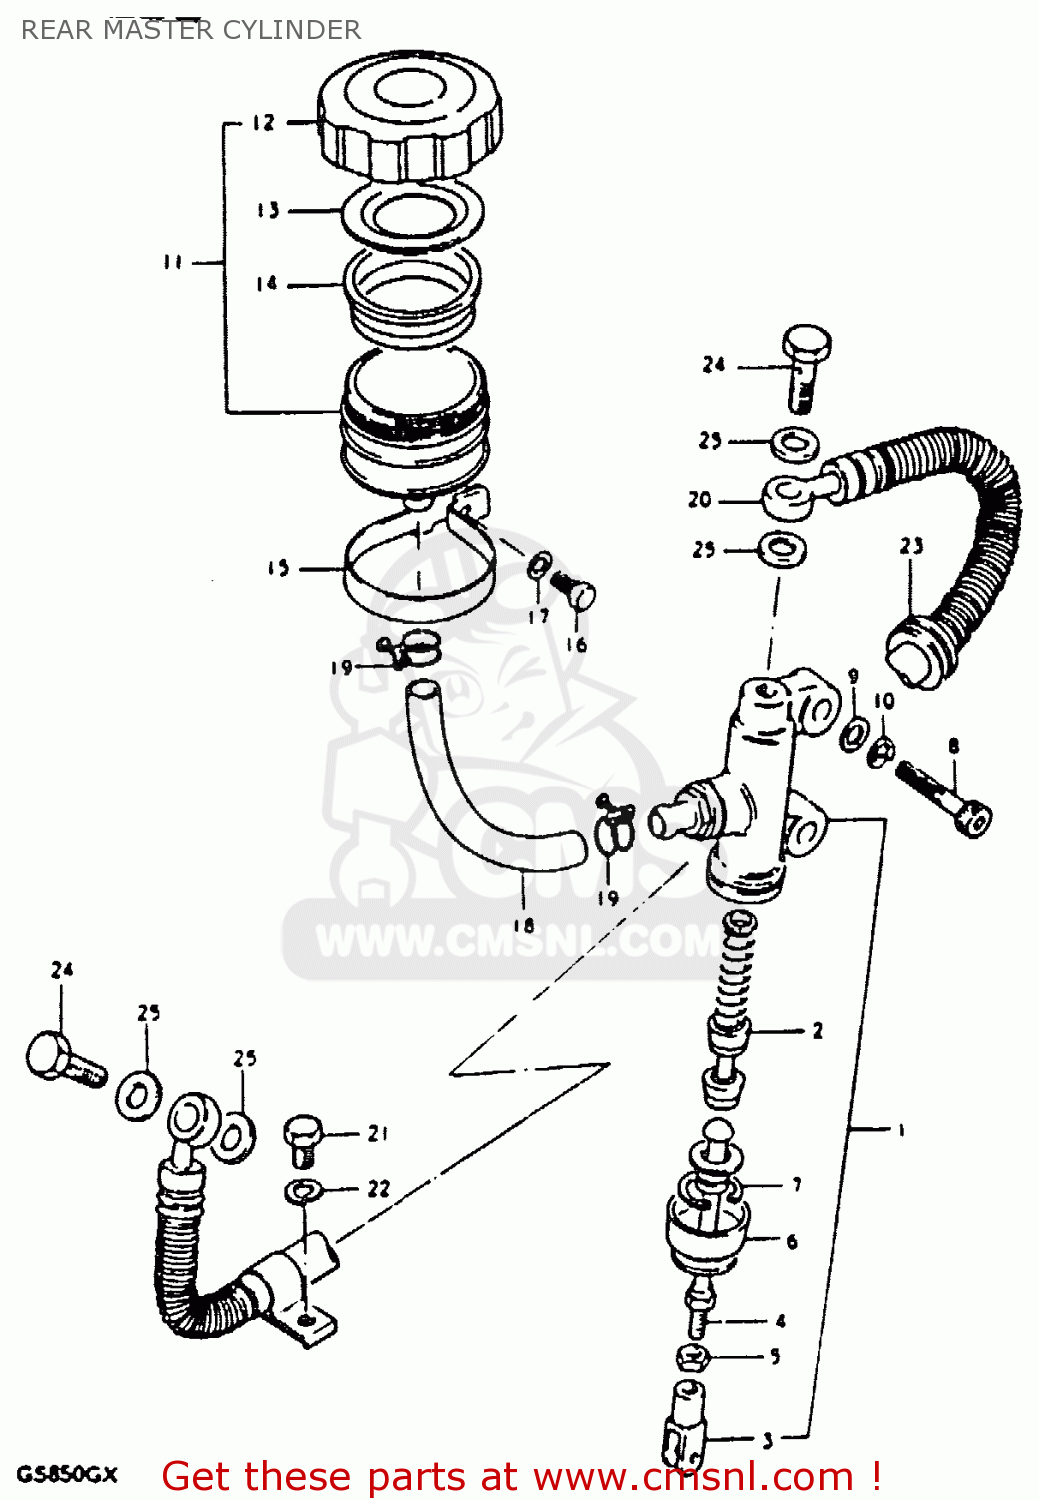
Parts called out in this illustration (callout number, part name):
1	CYLINDER ASSEMBLY,REAR MASTER
2	PISTON/CUP SET
3	YOKE
4	ROD,PUSH
5	NUT
6	BOOT
7	CIRCLIP
8	BOLT
9	WASHER
10	WASHER,LOCK,8.
11	TANK ASSEMBLY,RESERVOIR
12	CAP
13	PLATE,DIAPHRAGM
14	DIAPHRAGM
15	CLAMP
16	BOLT, UPPER
17	LOCK WASHER
18	HOSE,RESERVOIR TANK
19	CLAMP
20	HOSE,REAR BRAKE
21	BOLT
22	LOCK WASHER
23	GROMMET
24	BOLT,UNION
25	WASHER
